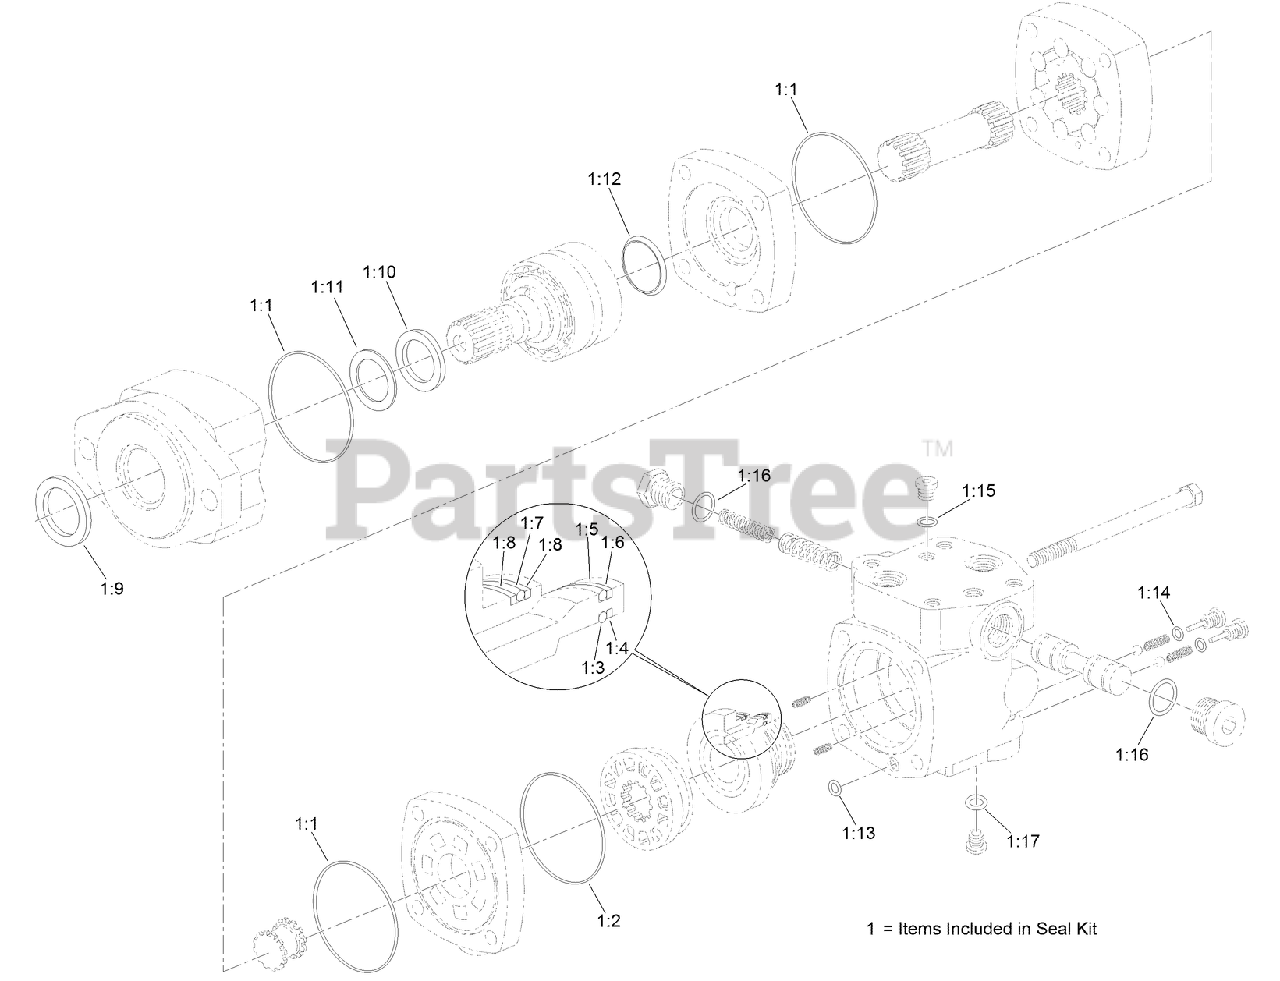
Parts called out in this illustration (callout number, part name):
1	SEAL KIT
1:1	O-RING
1:2	O-RING
1:3	O-RING
1:4	RING-BACKUP
1:5	O-RING
1:6	RING-BACKUP
1:7	O-RING
1:8	RING-BACKUP
1:9	SEAL
1:10	SEAL
1:11	Washer-Backup
1:12	Seal-Shaft Face
1:13	SEAL
1:14	O-RING
1:15	O-RING
1:16	O-RING
1:17	O-RING
